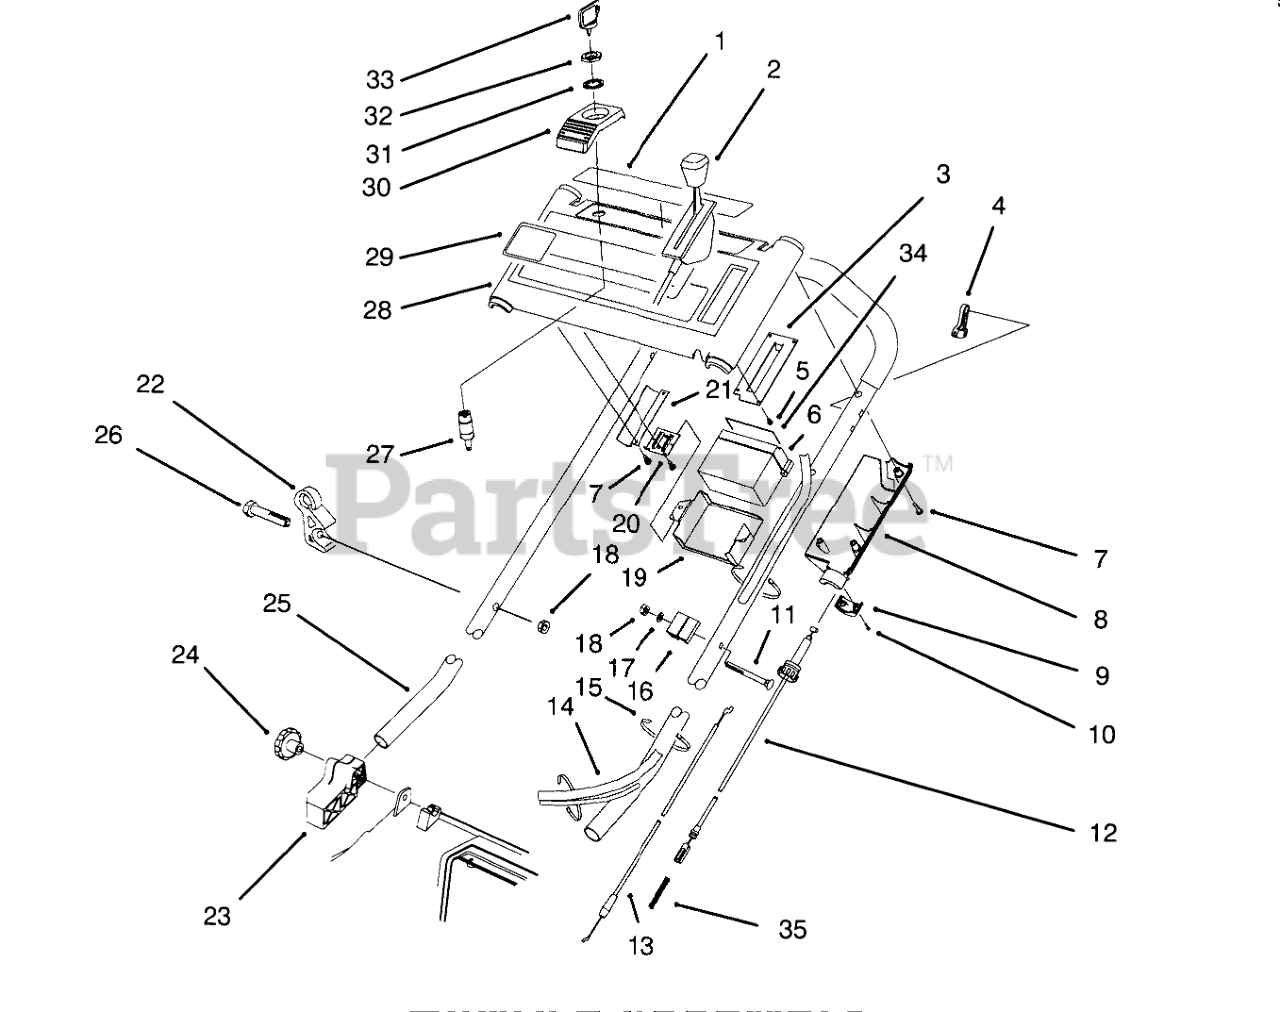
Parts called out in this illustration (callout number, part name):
1	DECAL - INSTRUCTION
2	CONTROL - THROTTLE
3	THROTTLE PLATE
4	LEVER-TRACTION
5	#6-19X.25 PLASK FORM SC
6	BATTERY ASSEMBLY
7	SCREW-PPH, PLASTITE
8	COVER-THROTTLE, LEVER
9	LOWER THROTTLE CAP
10	#4-14X.62 PLASTITE SCW
11	SCREW-HANDLE
12	CABLE - TRACTION
13	CABLE - BRAKE
14	Harness-Wire
15	TIE-CABLE
16	SUPPORT-CABLE
17	WASHER-FLAT
18	NUT-LOCK, NI
19	Retainer-Battery
20	BATTERY BRACKET
21	Bracket-Panel
22	GUIDE - ROPE
23	MOUNT-HANDLE, RH
25	HANDLE (DIPPED)
26	.250-20X1.625 HH SCREW
27	Switch-Starter (Incl. Ref. #31 & 32)
28	Panel-Control (Incl. Ref. #1 & 29)
29	DECAL - PANEL KEY
30	IGNITION SWITCH BRACKET
31	WASHER-TOOTH, INTERNAL
32	NUT-HH
33	KEY-IGNITION
34	DECAL-BATTERY
35	SPRING-COMPRESSION
